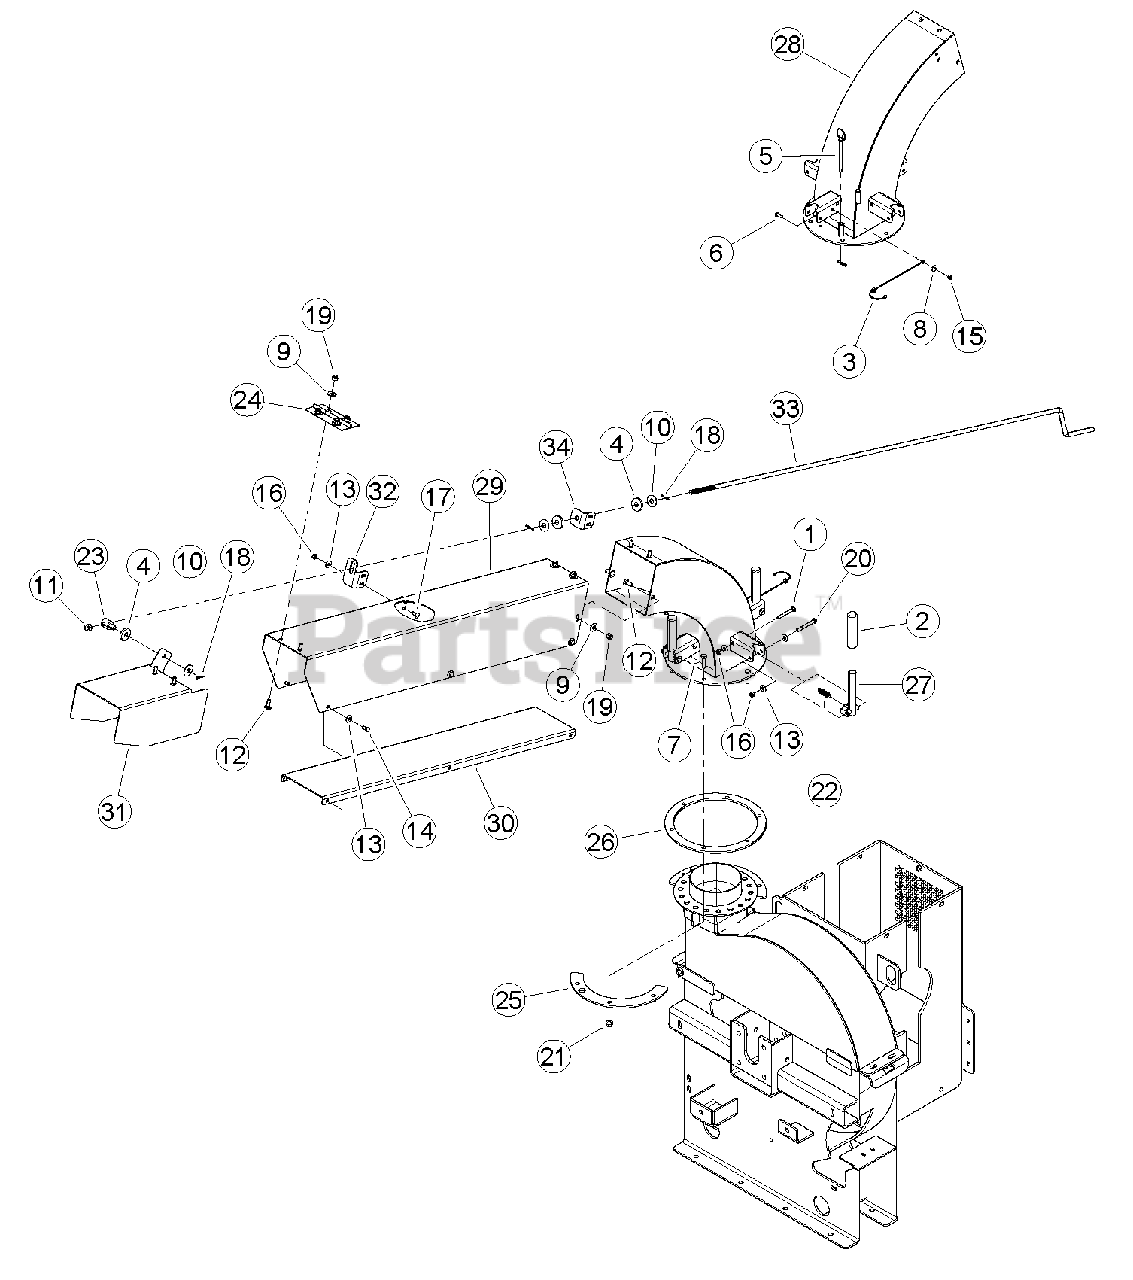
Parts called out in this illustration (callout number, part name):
1	BOLT, 5/16 X 2-1/2 CRG GR5 ZP
2	GRIP, TILT CONTROL
3	LANYARD, NYLON
4	WASHER, UHMW SPACER .515ID X 1.50OD
5	PIN, 3/8 HITCH
6	BOLT, 1/4 X 3/4 HEX GR5 ZP
7	BOLT, 3/8 X 1-1/2 HEX GR5 ZP
8	WASHER, 1/4 FLAT ZP
9	WASHER, 3/8 FLAT ZP
10	WASHER, 1/2 FLAT ZP
11	NUT, 1/2 CENTERLOCK GRB ZP
12	BOLT, 3/8 X 1 CRG GR5 NC ZP
13	WASHER, 5/16 FLAT ZP
14	BOLT, 5/16 X 5/8 HEX GR5 ZP
15	NUT, 1/4 NE NYLOCK ZP
16	NUT, 5/16 NE NYLOCK ZP
17	BOLT, 5/16 X 3/4 CRG GR5 NC ZP
18	PIN, 1/8 X 1.00 COTTER ZP
19	NUT, 3/8 NE NYLOCK ZP
20	BOLT, 5/16 X 2-3/4 HEX GR5
21	NUT, 3/8-16 NYLOCK FLANGE
22	SPRING, 1/2 X 2.00 LG ZP
23	PIVOT, HEIGHT ADJUSTMENT
24	HINGE, DISCHARGE CAP
25	RETAINER, DISCHARGE
26	SPACER, DISCHARGE CHUTE
27	WELDMENT, HANDLE
28	WELDMENT, DISCHARGE CHUTE
29	CHANNEL, DISCHARGE CHUTE
30	WELDMENT, DISCHARGE BOTTOM
31	CAP, DISCHARGE
32	STRIP, DISCHARGE
33	CRANK, DISCHARGE
34	BRACKET, DISCHARGE CRANK
